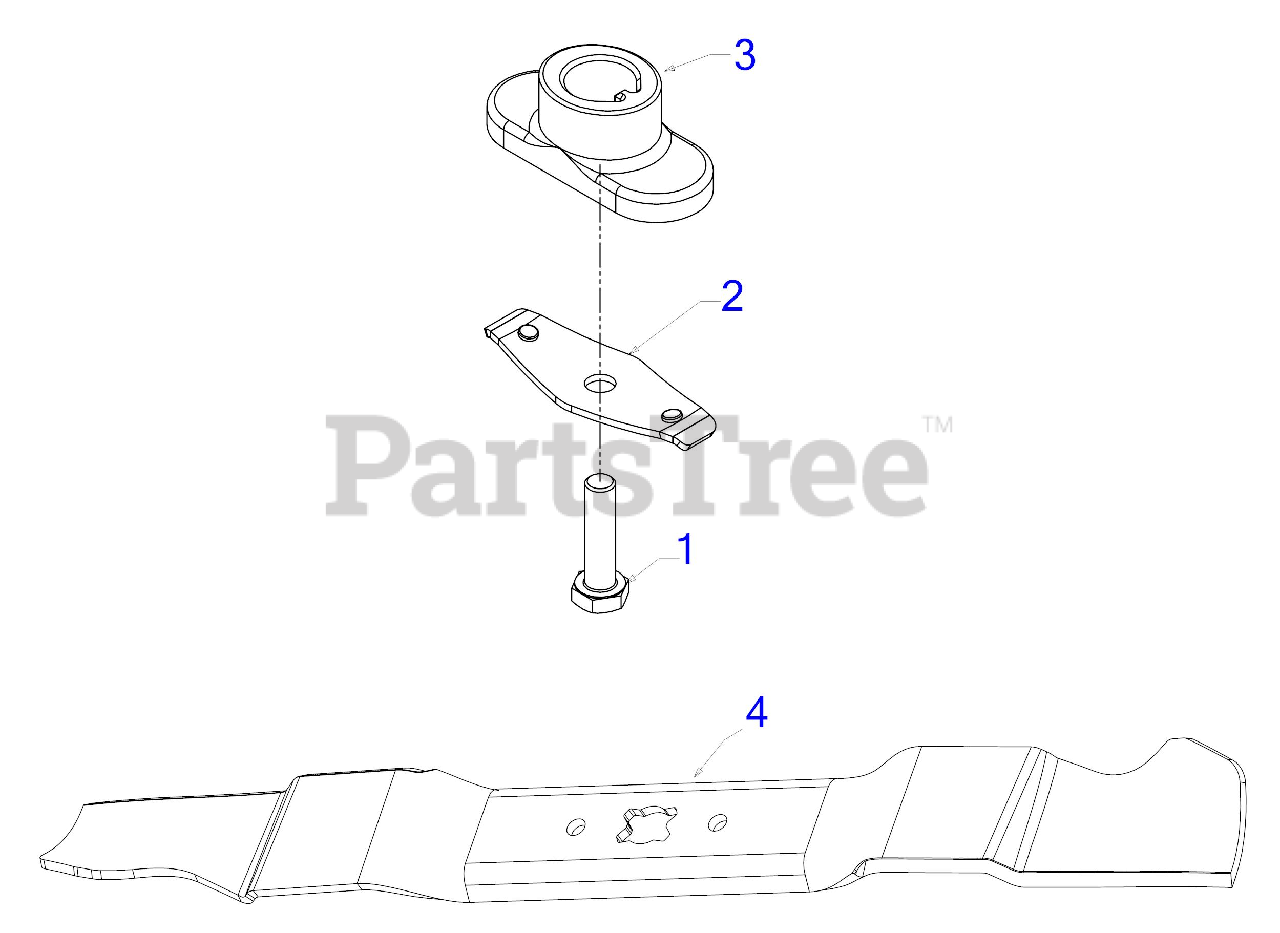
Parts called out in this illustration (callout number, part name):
1	SCREW 3/8-24 x 1.50 GR8
2	BLADE BELL SUPPORT
3	BLADE ADAPTER-W/STAR
3	BLADE ADAPTER KIT
4	21" BLADE (MULCH)
4	Genuine Factory Parts 21" MULCH BLADE
4	Cub Cadet 21" MULCH BLADE
4	Genuine Factory Parts 21" MULCHING BLADE (0741A)
4	21" BLADE (MULCH) (XTREME)
